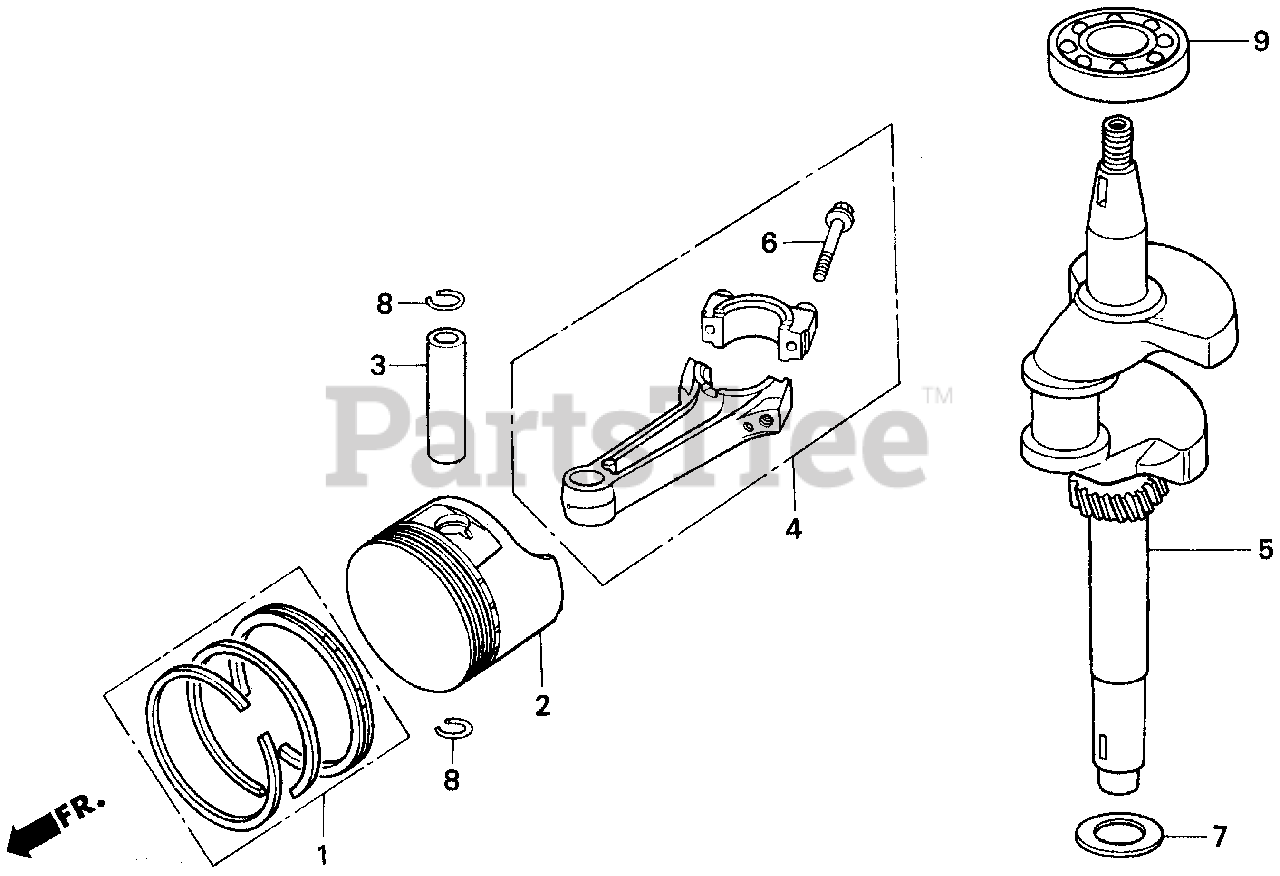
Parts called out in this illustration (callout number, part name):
1	RING SET, PISTON (STD)
1	RING SET, PISTON (STD) (FEDERAL MOGUL)
1	RING SET, PISTON (STD) (TEIKOKU)
1	RING SET, PISTON (OS 0.25)
1	RING SET, PISTON (OS 0.50)
1	RING SET, PISTON (OS 0.75)
2	PISTON (STD)
2	PISTON (OS 0.25)
2	PISTON (OS 0.50)
2	PISTON (OS 0.75)
3	PIN, PISTON
4	ROD ASSY., CONNECTING
5	CRANKSHAFT
6	BOLT, CONNECTING ROD
7	WASHER C, THRUST (25MM)
8	CLIP, PISTON PIN (13MM)
9	BEARING, RADIAL BALL (62/22)
